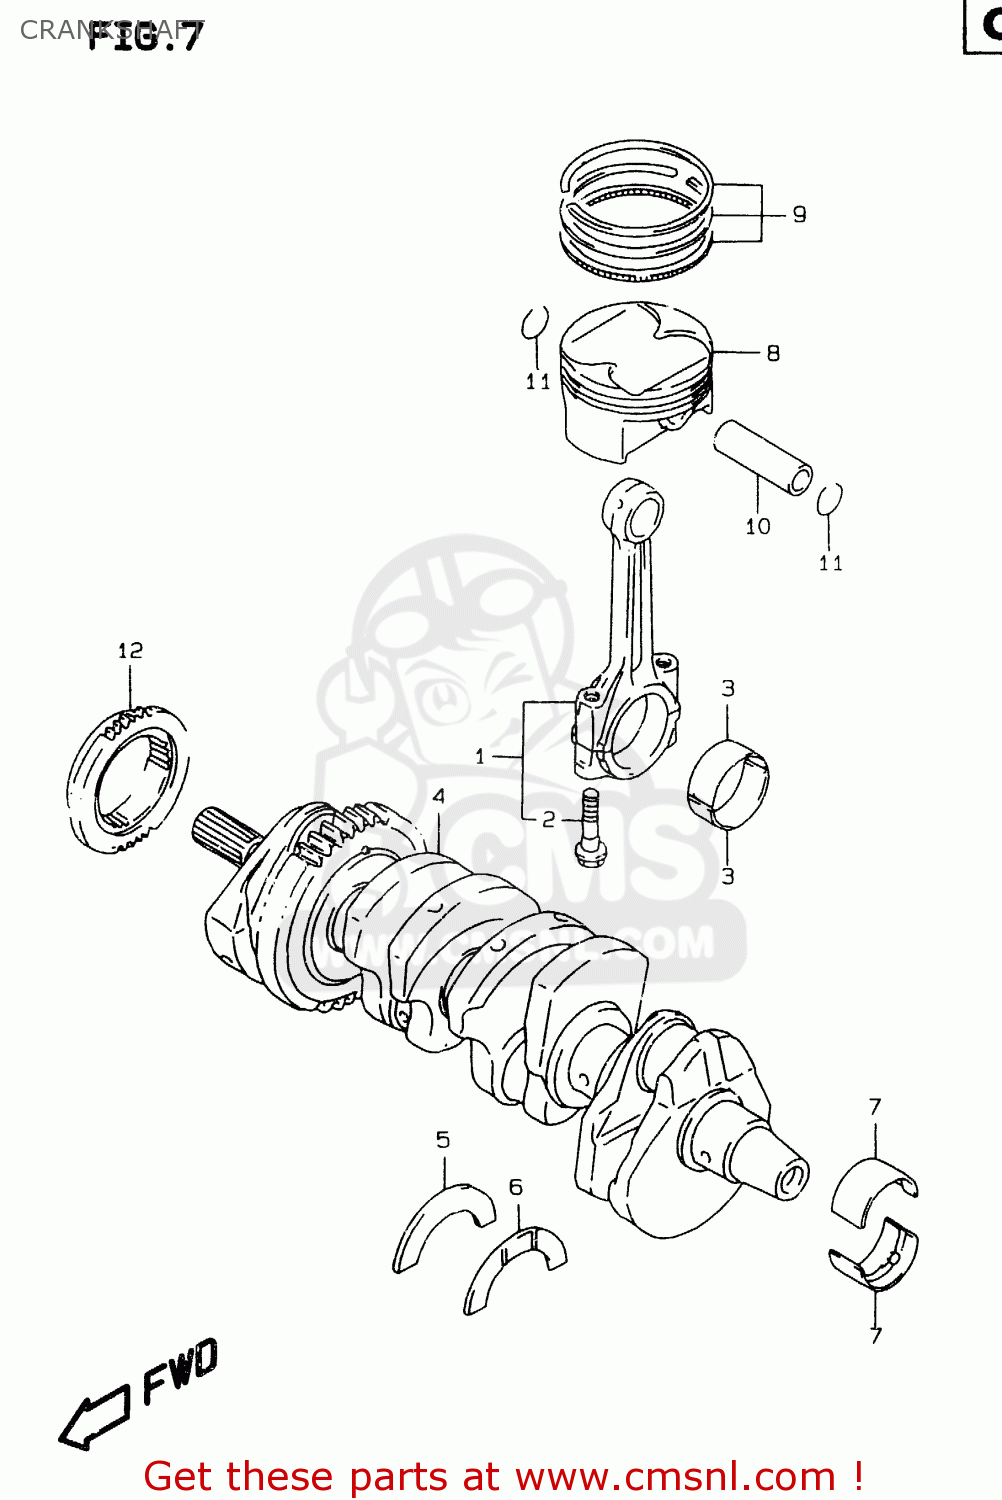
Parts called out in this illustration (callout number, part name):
1	CONNECTING ROD ASSEMBLY
2	BOLT,CONNECTING ROD
3	BEARING,CRANK PIN
4	CRANKSHAFT SET
5	BEARING,CRANK THRUST(GREEN)
6	BEARING,CRANK THRUST(RED)
7	BEARING,CRANKSHAFT(GREEN)
8	PISTON
9	RING SET,PISTON
10	PIN,PISTON
11	CIRCLIP
12	SPROCKET,CAM CHAIN DRIVE
